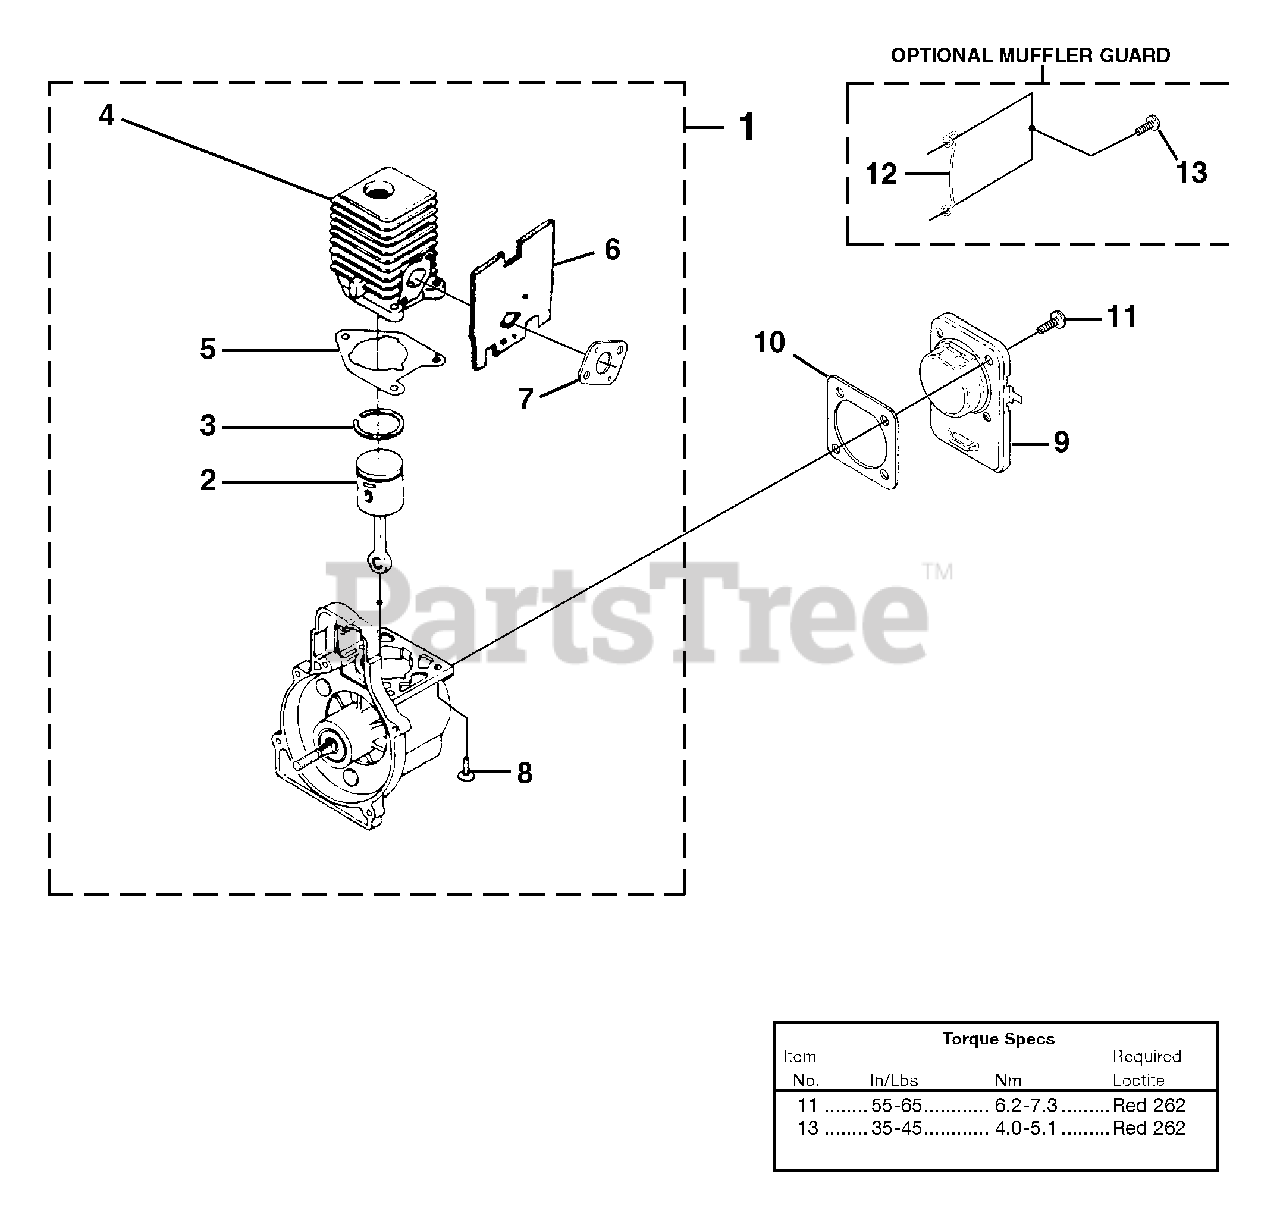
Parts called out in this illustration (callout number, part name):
1	SHORT BLOCK ASSY.
2	PISTON & ROD ASSY.
3	RING-Piston
4	CYLINDER
5	GASKET-Cylinder
6	GASKET-Heat Dam
7	GASKET-Carburetor
8	SCREW-Sems (12-24 X 3/4")
9	CRANKCASE COVER
10	GASKET-Crankcase Cover
11	SCREW-Sems (10-24 X 1/2")
12	MUFFLER GUARD
13	SCREW-Thread Forming (10-14 X 1/2")
